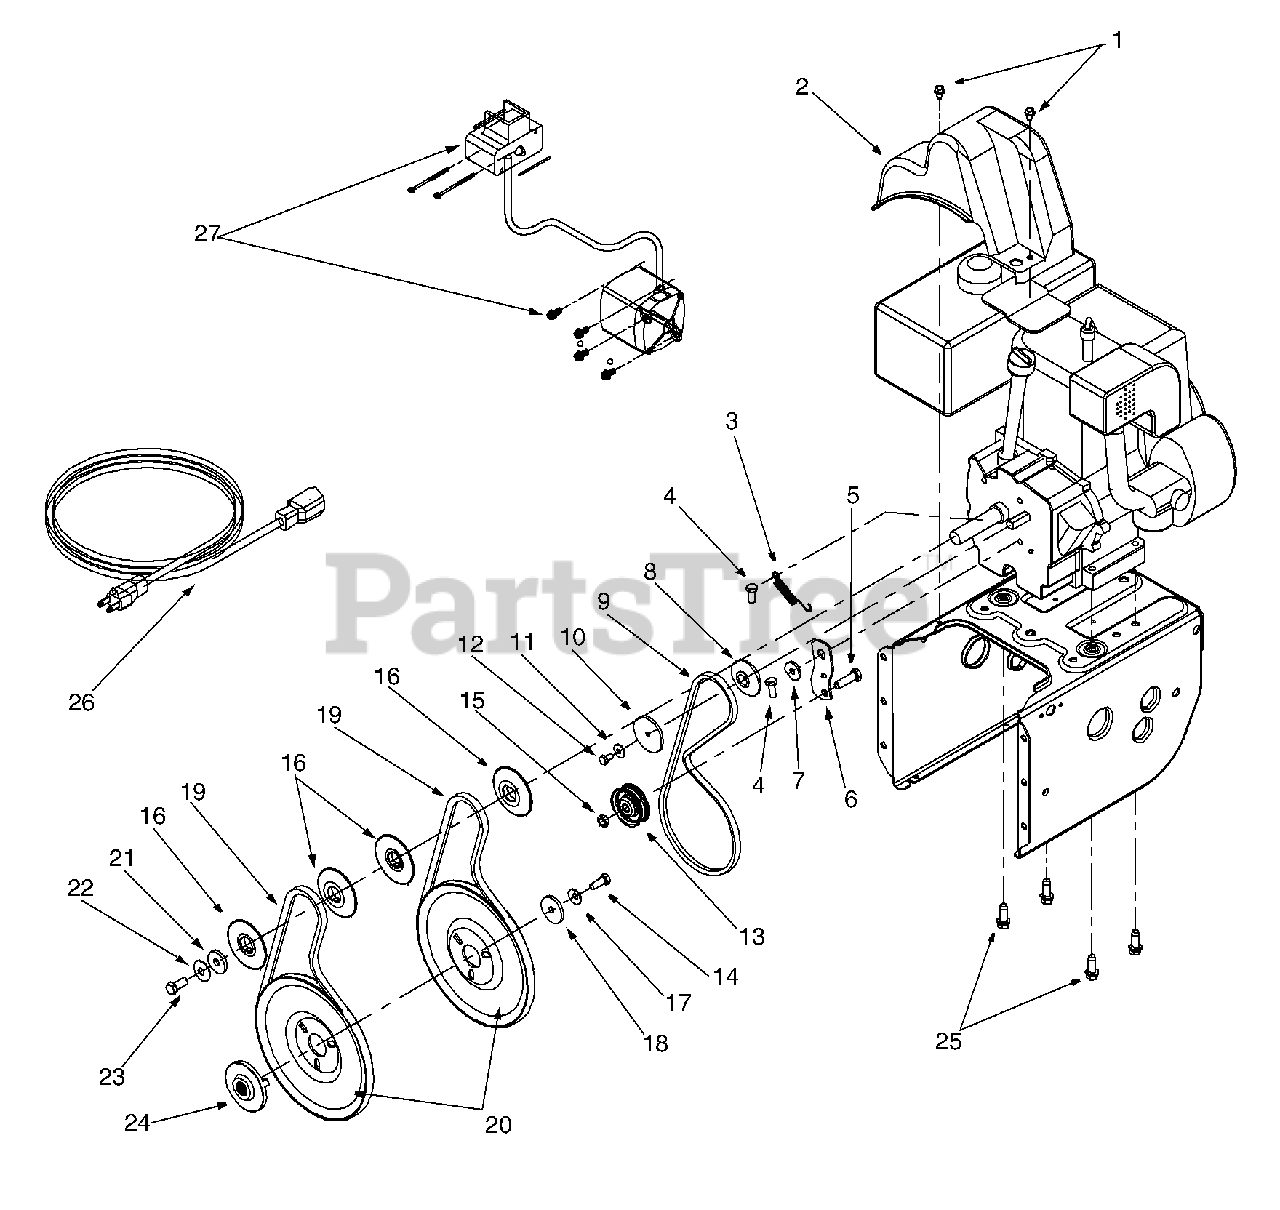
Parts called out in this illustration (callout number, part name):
1	Hex Washer Screw 1/4-20 x .50
2	Belt Cover
3	Extension Spring
4	Hex Screw 5/16-24 x .75
5	Hex Cap Screw 3/8-16 x 1.25
8	Pulley Half
9	V-Belt
10	Pulley Half
11	Bell Washer
12	Hex Cap Screw 1/4-28 x .50
13	Flat Idler
14	Lock Hex Cap Screw 5/16-24
15	Lock Jam Nut 3/8-16
16	Pulley Half
17	Bell Washer
18	Flat Washer
19	Belt
20	Auger Pulley
21	Flat Washer 3/8 x 1.25 OD
22	Bell Washer
23	Hex Cap Screw 3/8-24
24	Adapter Pulley
25	Hex Tap Screw, 3/8-16 x 1
26	Extension Cord
27	Electric Start Kit
